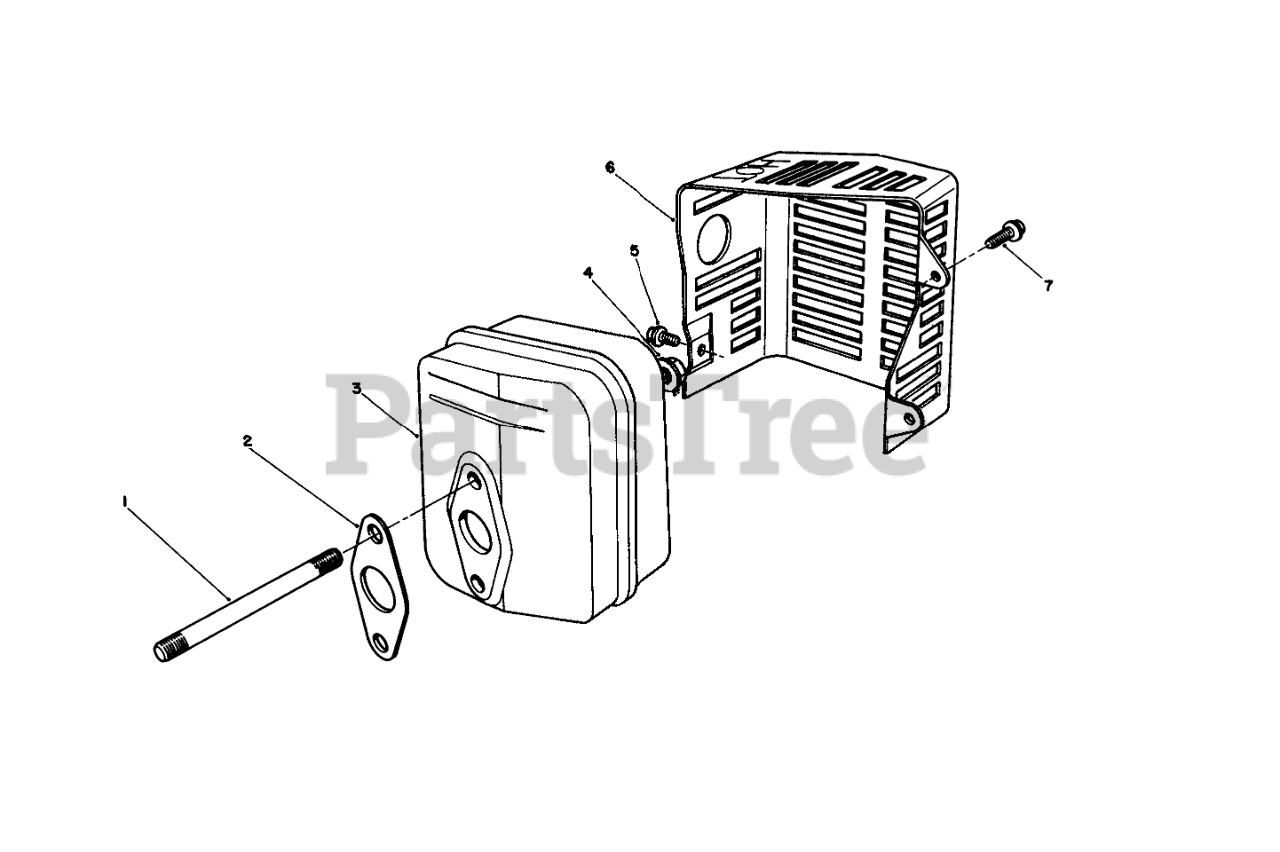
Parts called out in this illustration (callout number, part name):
2	GASKET
3	MUFFLER
5	SCREW
6	COVER
